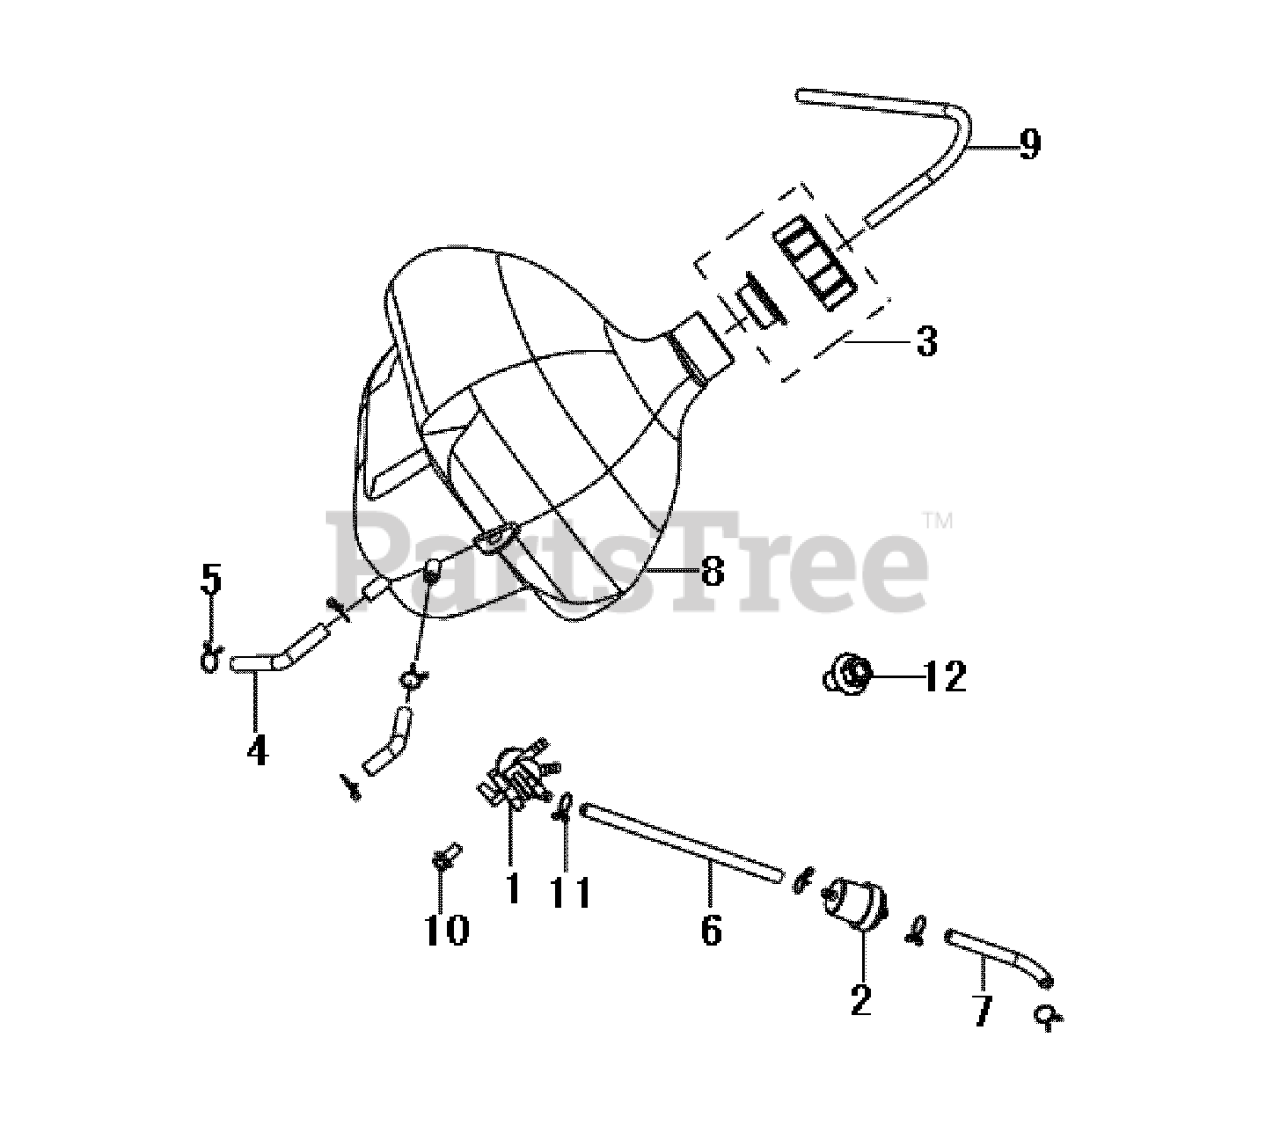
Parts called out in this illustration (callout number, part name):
1	FUEL VALVE ASSY.
2	FUEL FILTER ASSY.
3	FUEL TANK CAP ASSY.
4	FUEL LINE
5	CLAMP, FUEL LINE
6	FUEL LINE
7	FUEL LINE
8	FUEL TANK
11	CLAMP, FUEL LINE
